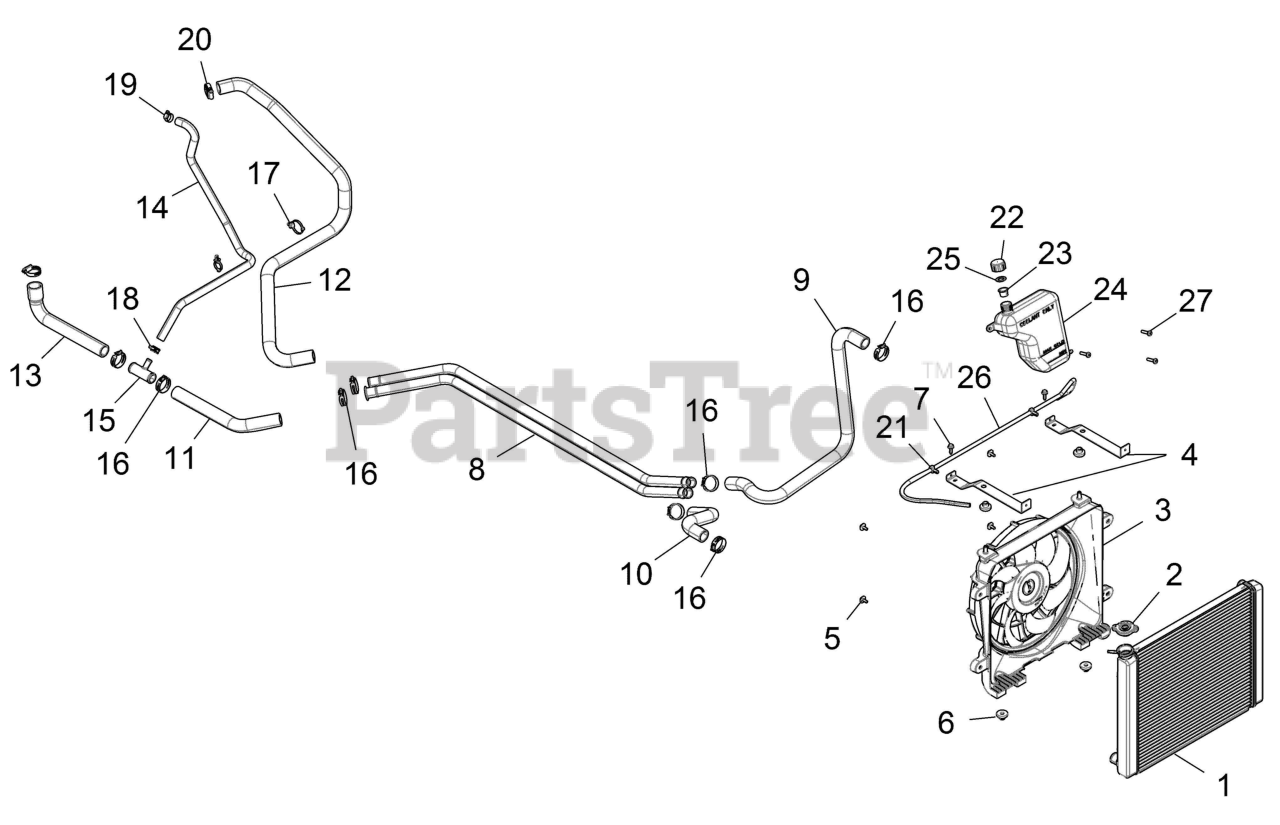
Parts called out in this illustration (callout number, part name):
1	ASM-RADIATOR,CORE
3	FAN-ASSEMBLY
4	MOUNT, RADIATOR, BLACK
5	BOLT-M6X15MM
7	SCR-M6X1.0X20,HXHD,FLG,TDFM,BL
8	TUBE, COOLANT, CREW, 1 IN
9	HOSE-UPPER,RAD
10	HOSE-LOWER,RAD
11	HOSE-ENG,IN
12	HOSE-ENG,OUT
13	HOSE-ENG,INLET/BYPASS
14	HOSE-BYPASS
15	CONNECTOR-TEE,1X1X0.5
16	CLAMP,SPRINGBAND 35/12,BLK
17	CLIP-ROUTING
18	CLAMP-HOSE,SPRING,20MM
19	CLAMP, HOSE (10)
20	CLAMP-HOSE(WORM DR)25-40MM
22	CAP, OVERFLOW
23	CAP,PLUG9X(GRN),FLEX TEMP(10)
24	TANK-SURGE
25	GASKET (10)
26	FUEL LINE-95 CENTIMETERS
27	SCR-#14X1 HI/LO-PH-PN TRX-M
